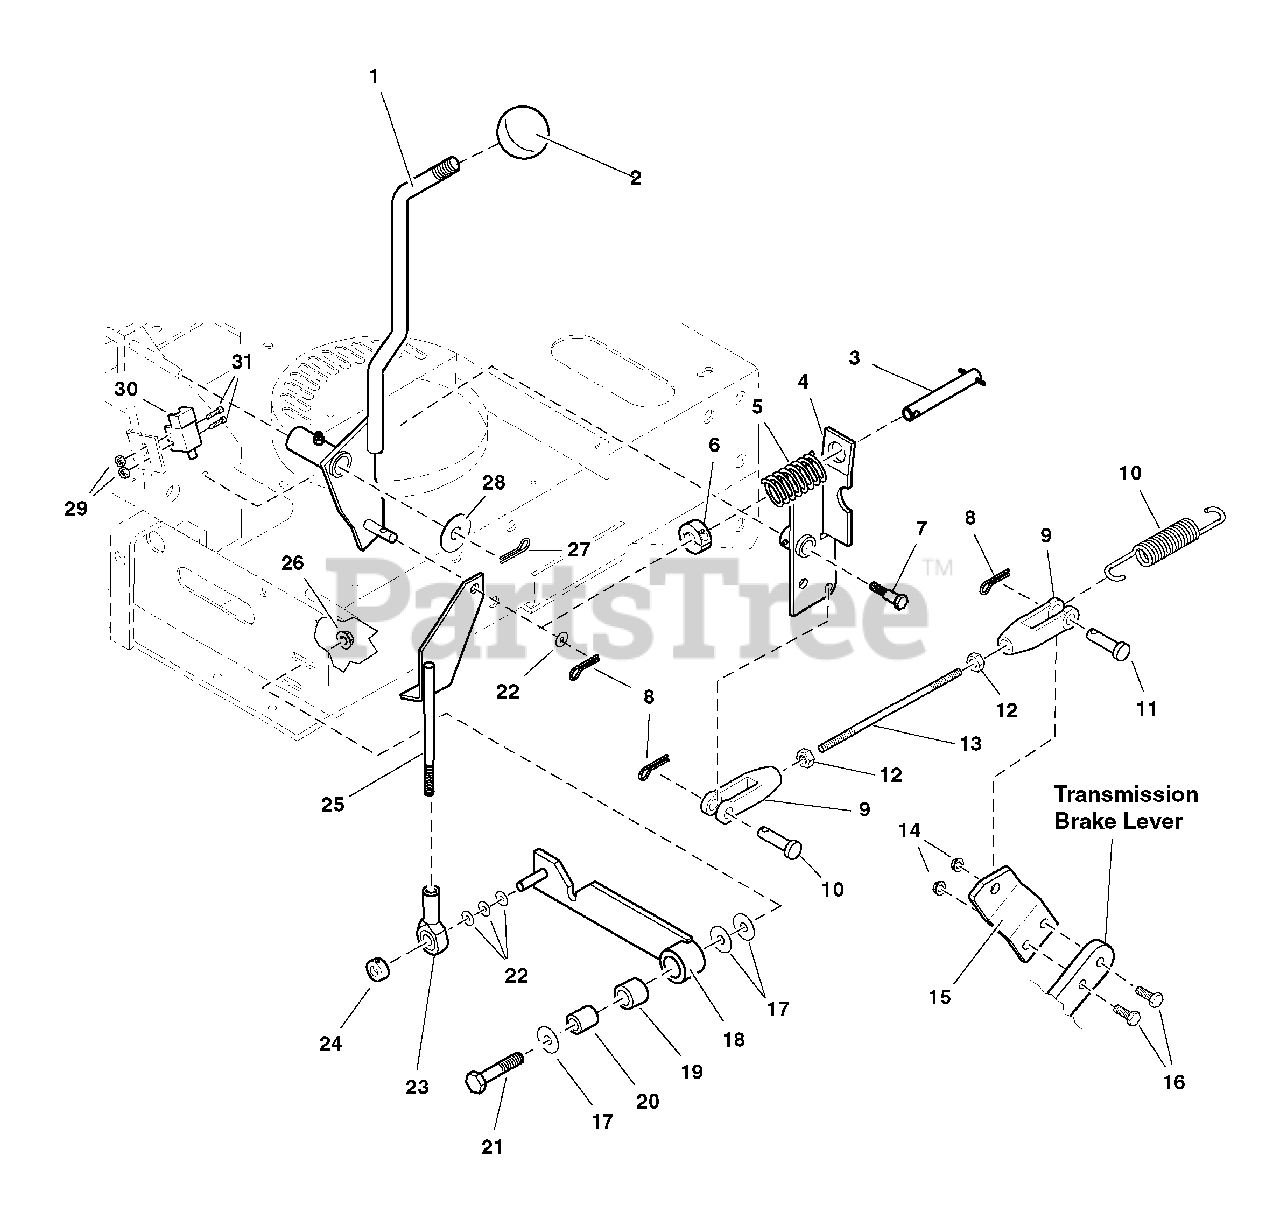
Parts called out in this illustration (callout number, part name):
1	PARKING BRAKE LEVER
3	SPRING BAR ASSEMBLY
4	BRAKE ROCKER ARM
5	SPRING, Compression
6	COLLAR, Set, 5/8
7	CAPSCREW, Allan Head, Shoulder, 3/8-16 x 1/2 x 1
8	PIN, Cotter
9	CLEVIS. Plastic, 5/16-24
10	SPRING, Extension
12	NUT, Hex, 5/16-24
13	BRAKE LINKAGE ROD
14	NUT, Hex, Nylon Lock, 1/4-20
15	BRAKE LEVER
16	BOLT, 1/4-20 X 1", GD
17	WASHER, Fender, 5/16
18	NEUTRAL LOCK LEVER, complete (includes Ref 19)
19	BUSHING, Brass
20	PIVOT SLEEVE
21	CAPSCREW, Hex Hd, 5/16-18 x 2
22	WASHER, 5/16
23	BALL JOINT 5/16-24 RH FEMALE STAMPED STL
24	COLLAR, Set, 5/16
25	BRAKE LOCK LINK
26	NUT, Hex, Serrated Flange, 5/16-18
28	WASHER, 5/8
29	NUT, Hex, #10-24
30	SWITCH, PLUNGER, N.O./N.C.
31	Screw, #10-24 x 1"
